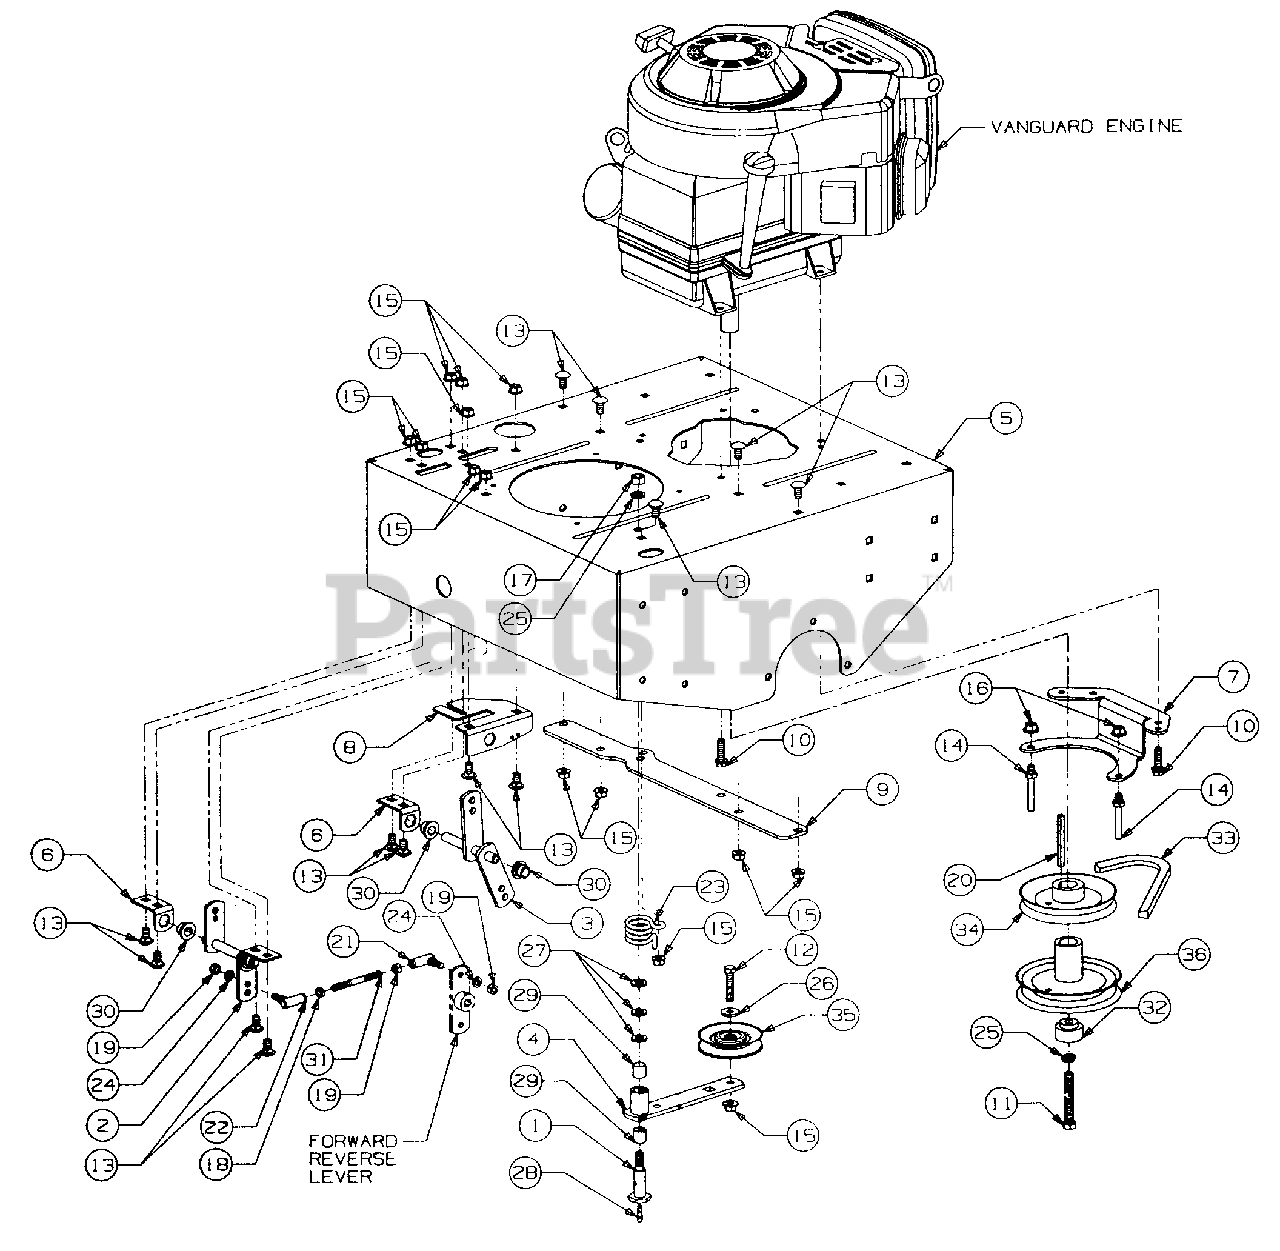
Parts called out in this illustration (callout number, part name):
1	Bolt, Shoulder
2	Lever, F/R Control
3	Lever, PTO Engagement
4	Arm Assy, Idler [Includes Ref No. 29 (Qty 2)]
5	Deck, Engine Mtg
6	Bracket, Lever Angle
7	Retainer, Belt Guide
8	Plate, Engagement Lever Mtg
9	Stiffener
10	Screw, Hex L-Wash Tapp, 3/8-16 X 1.25 Lg
11	Screw, Hex Cap, 7/16-20 X 3.0 Lg GR5
12	Screw, Hex Cap, 3/8-16 X 1.75 Lg
13	Bolt, Sht Nk Carriage, 3/8-16 X .75 Lg GR5
14	Stud, 3/8-16 X 2.68 Lg
15	Nut, Hex Flanged Lock, 3/8-16
16	Nut, Hex Flange Lock, 3/8-16 GR5
17	Nut, Hex, 7/16-14 GR5
18	Nut, Hex Cap, 5/16-24 LH Thread
19	Nut, Hex, 5/16-24 GR5
20	Key, Square, 1/4 X 3.0 Lg
21	Ball Joint, 5/16-24
22	Ball Joint, 5/16-24 LH Thread
23	Spring, Torsion
24	Washer, Lock, 5/16
25	Washer, Lock, 7/1
26	Washer, Special, .378 X 1.00 X .125 Thk
27	Washer, Flat, .469 X .875 X .105 Thk
28	Fitting, Lube
29	Bearing, Sleeve
30	Bearing, Hex Flange
31	Rod, Control
32	Plug, Pulley
33	Belt, Transmission, 1/2 X 40.0 Lg
34	Pulley, Engine
35	Pulley, V-Idler
36	Pulley, PTO Drive
